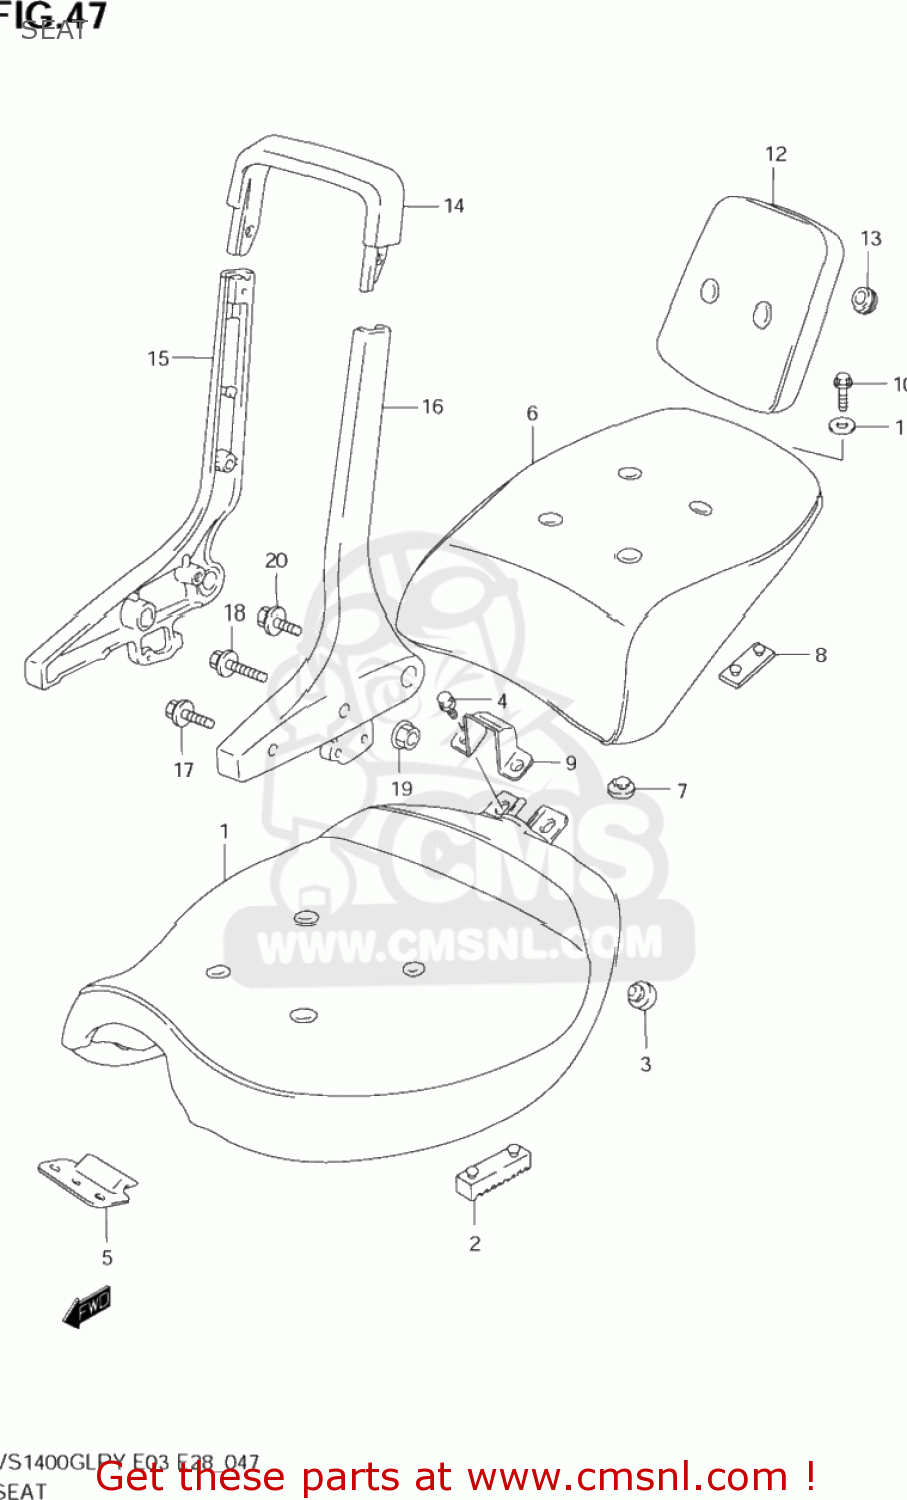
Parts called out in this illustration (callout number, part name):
1	SEAT ASSY
2	CUSHION,SEAT
3	CUSHION
4	BOLT
5	BRACKET,SEAT FR
6	SEAT ASSY,PILLION
7	CUSHION
8	CUSHION,PILLION SEAT RR
9	BRACKET,PILLION SEAT FR
10	BOLT(6X17.5)
11	WASHER(9.5X20X1)
12	PAD ASSY,SEAT
13	CUSHION
14	HANDLE,PILLION RIDER UPR
15	HANDLE,PILLION RIDER,RIGHT
16	HANDLE,PILLION RIDER,LEFT
17	BOLT, FRONT
18	BOLT
19	NUT
20	BOLT, REAR
